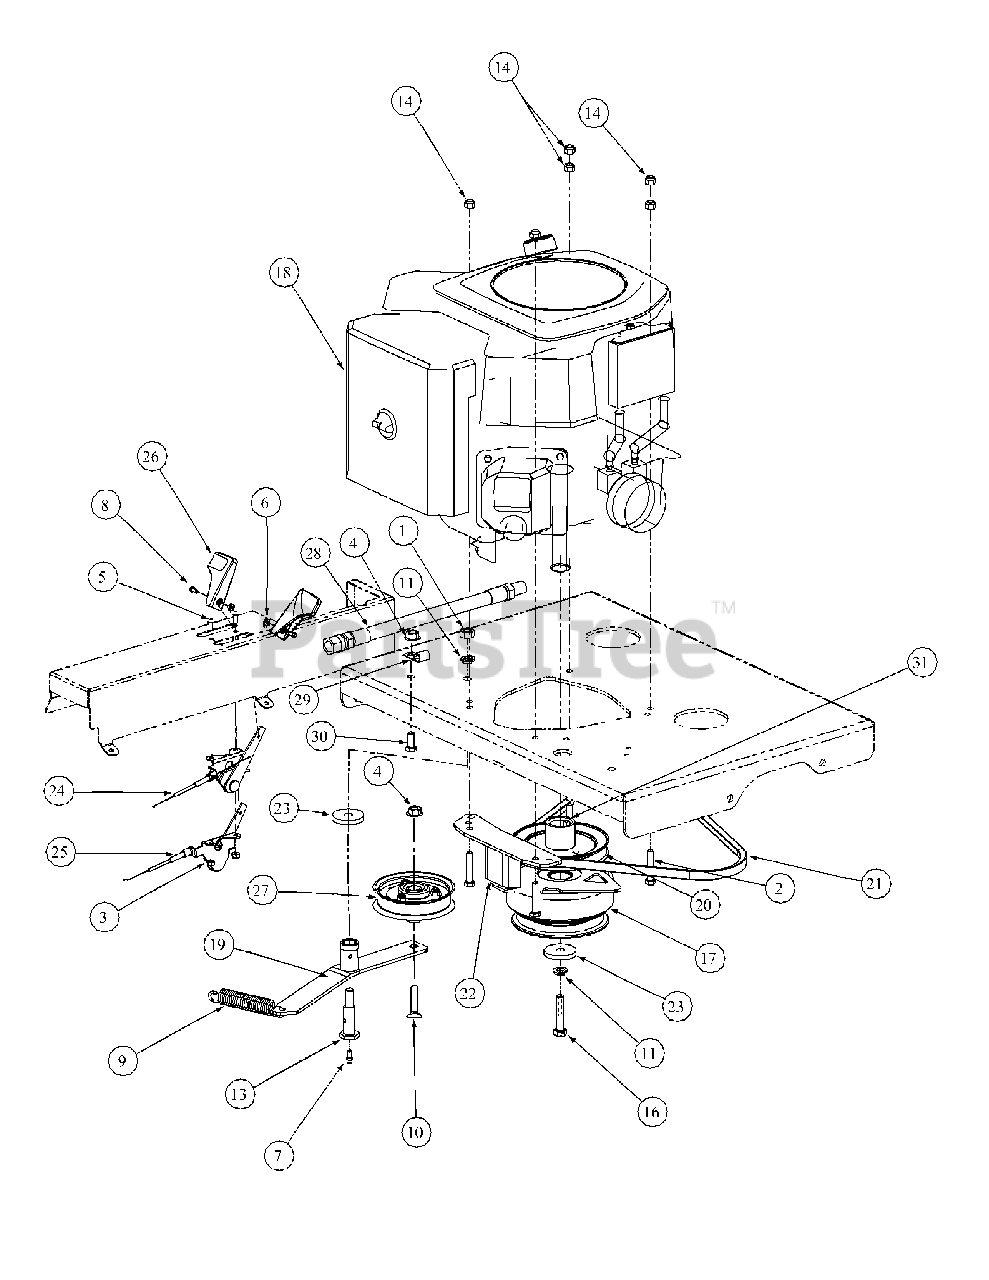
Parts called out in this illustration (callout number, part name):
1	Hex Nut, 7/16-14
2	HHCS, 5/16-18, 1-3/4
3	Nut, Lock, Nylon Insert, #10-32
4	Hex Nut, 3/8-16, Range Lock
5	Screw, Machine 10-32 x 3/4
6	Nut, Washer, 8-32
7	Grease Fitting, 1/4-28 x 3/16
8	Machine Screw, 8-32, .375
9	Extension Spring, 1.0 OD x 5.125
10	Screw, 3/8-16, 1.75, Hex Carriage
11	Lock Washer, 7/16
13	Shoulder Bolt
14	Lock Nut, Hex Flange, 5/16-18
16	Capscrew, 7/16-20 x 2"
17	Clutch, Brake, 1.125" ID
18	Engine 25 HP, Kohler
19	Arm Assy Brg Idler Plated
19	Bearing
20	Drive Pulley, 5.0 Trans
21	V-Belt, A Section x 47.3
22	Retension Assembly, Ogura 1.125 ID Clutch
23	Flat Washer, 7/16 ID x 1.75 OD
24	Control Cable, 33.0 Choke
25	Control Cable, 45.0 Throttle
26	Knob, Throttle Control
27	Pulley, Idler, 4.06"
28	Hose, Kohler Oil Drain
29	Clip, Cable/Hose
30	HHCS, 3/8-16 x .750
31	Key, 1/4 x 1/4 x 2-1/2
